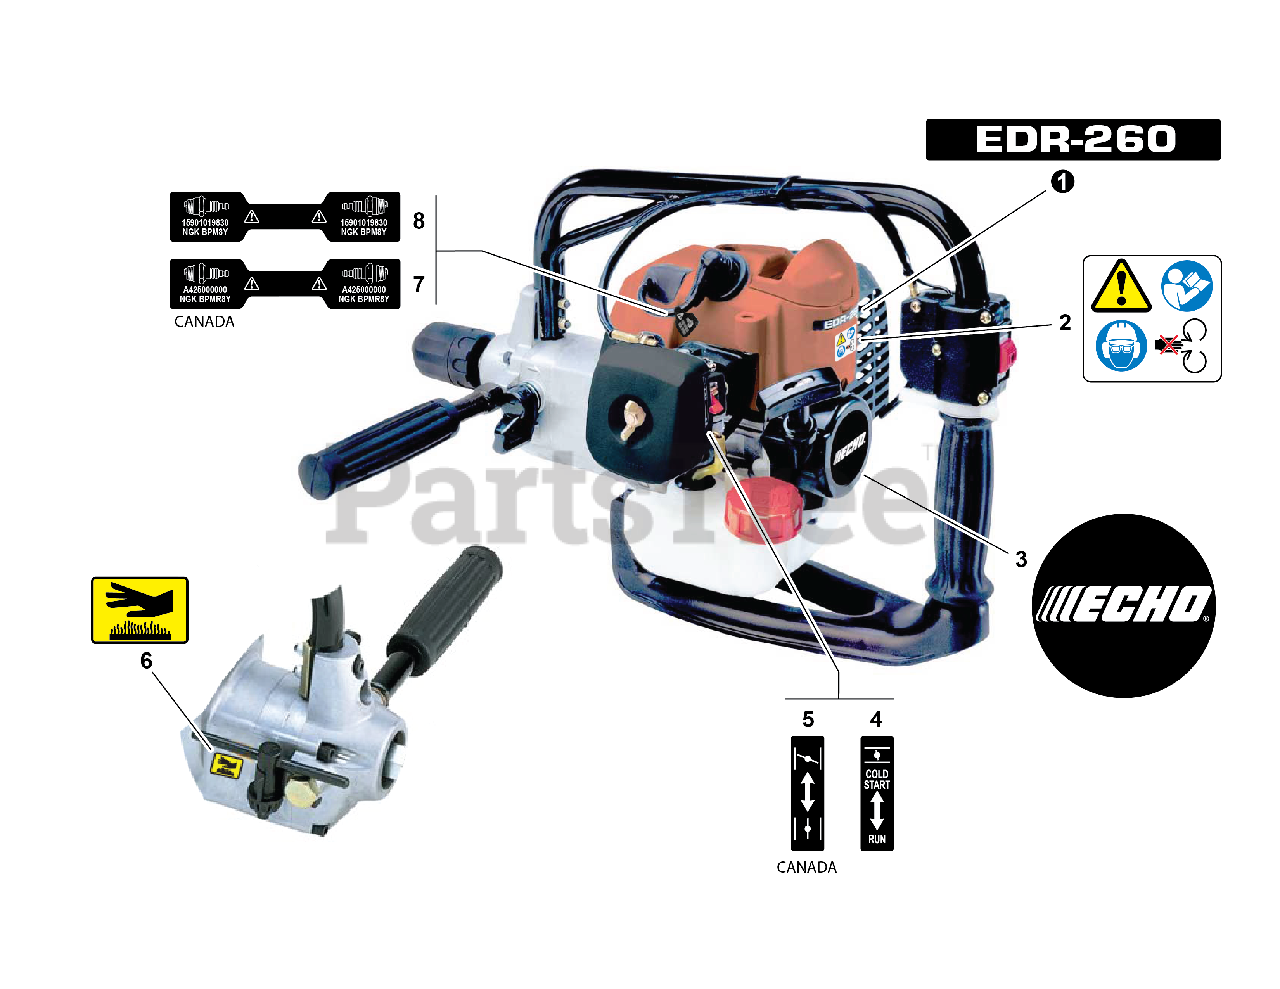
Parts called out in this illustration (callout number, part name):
1	LABEL - MODEL -- EDR-260
2	LABEL - CAUTION -- HOT
3	LABEL - ECHO
4	LABEL - CHOKE
5	LABEL - CHOKE
6	LABEL - CAUTION -- HOT
7	LABEL - SPARK PLUG -- BPMR8Y
8	LABEL - SPARK PLUG -- BPM8Y
